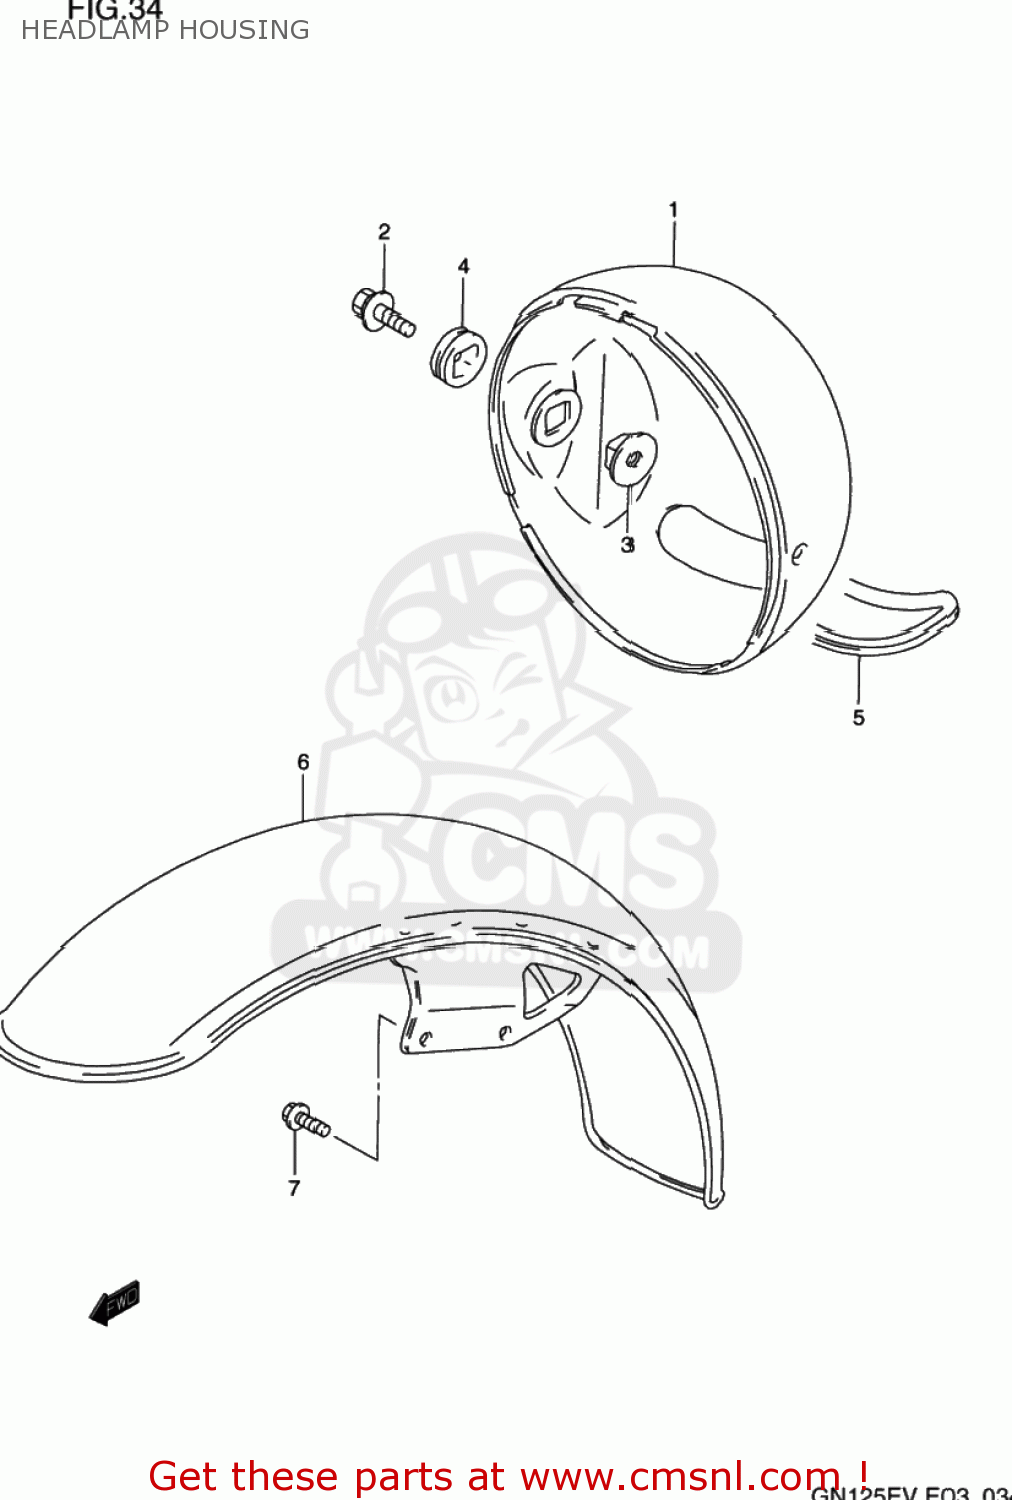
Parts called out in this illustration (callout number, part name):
1	HOUSING,HEADLAMP
2	BOLT
3	SPACER,HEADLAMP HOUSING
4	CUSHION,HEADLAMP HOUSING
5	MOLDING WINDSCREEN
6	FENDER,FR
7	BOLT, UPPER
